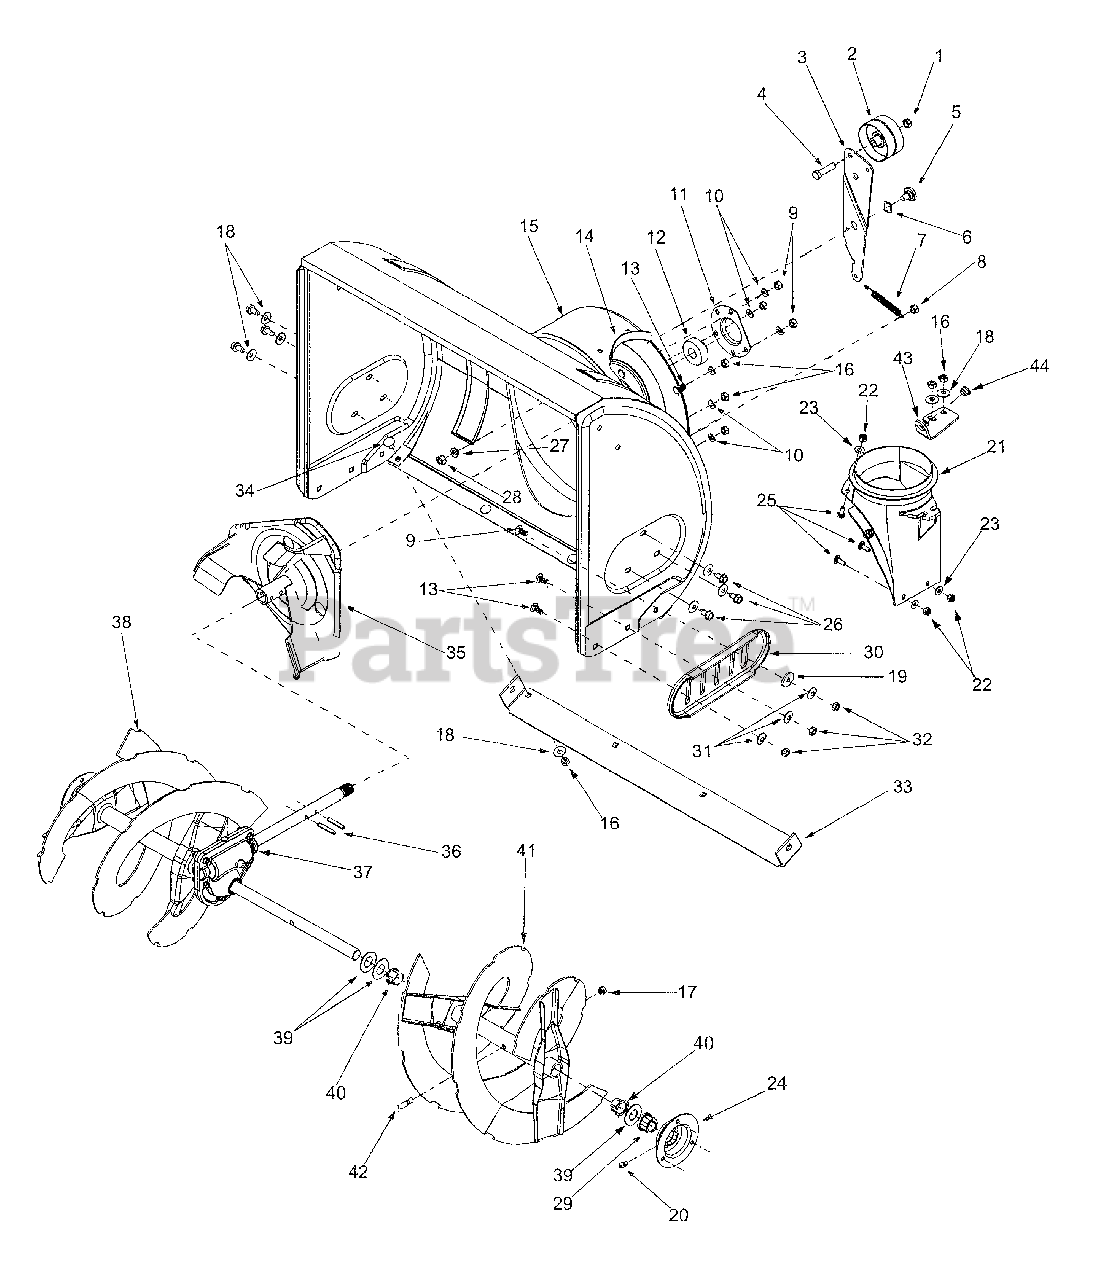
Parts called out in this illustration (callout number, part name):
1	Lock Jam Nut 3/8-2:4
2	Flat Idler
3	Auger Idler Arm
4	Hex Cap Screw 3/8-24 x 1.50
5	Shoulder Screw
6	Flat Washer .656 ID x 1.25 OD
7	Extension Spring
8	Hex Nut 5/16-18
9	Carriage Bolt, 5/16-18 x 1.00
10	Lock Washer 5/16
11	Housing
12	Ball Bearing
13	Carriage Bolt, 5/16-18 x .75
17	Lock Nut 5/16-18
18	Belleville Washer
19	Flat Wshr, .344 ID x 1.125 OD
20	Grease Fitting, 3/16" Drive
21	Chute Adapter
22	Hex Lock Nut 1/4-20
23	Flat Washer
24	Bearing Housing w/Fitting
25	Carriage Screw 1/4-20 x .75
26	Hex Screw 5/16-18
27	Lock Washer 3/8
28	Hex Nut 3/8-16
29	Hex Flange Bearing
30	Skid Shoe
31	Bell Washer
32	Hex Nut 5/16-18
33	Shave Plate
34	Carriage Bolt 5/16-18 x 1.00
35	Impeller Assembly
36	Pin
37	24" Gear Assy
40	Flange Bushing
41	24" Spiral LH
42	Shear Bolt 5/16-18 x 1.5
43	Chute Crank Bracket
44	Bushing
